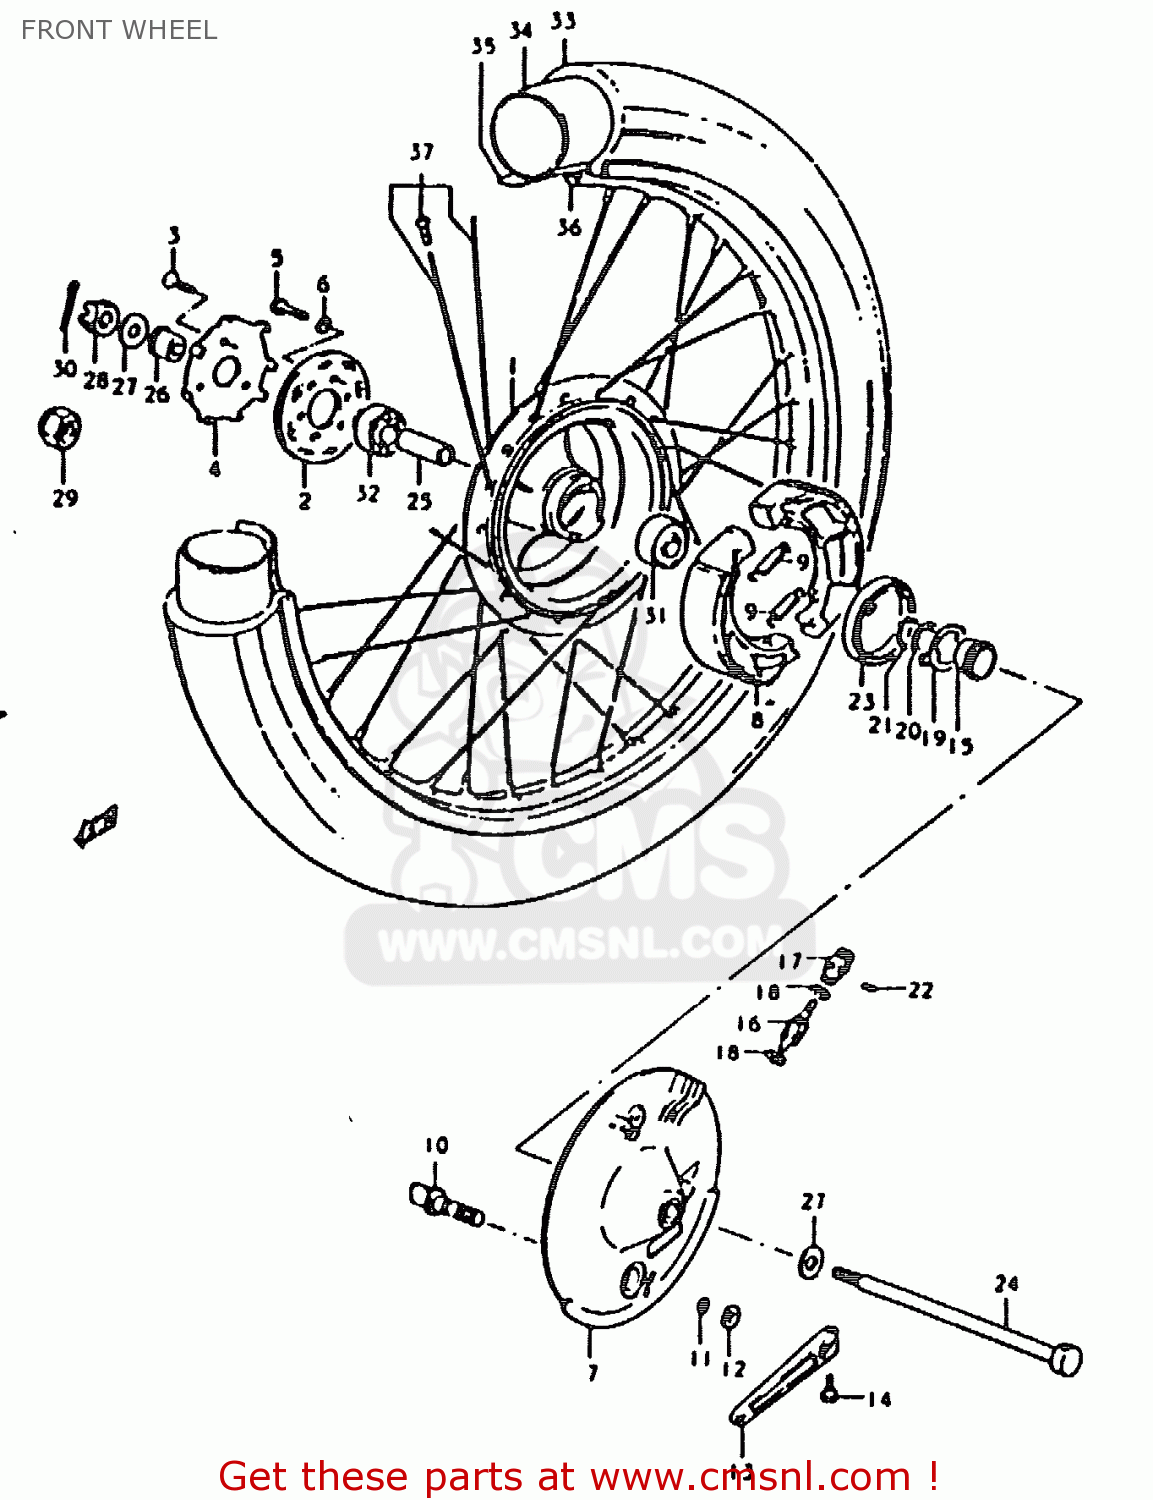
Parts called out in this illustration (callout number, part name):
1	HUB,FR WHEEL
2	FLANGE,FR HUB,R
3	SCREW
4	RETAINER,FR HUB BEARING,R
5	BOLT, UPPER
6	LOCK WASHER
7	PANEL,FRONT HUB
8	SHOE,BRAKE
9	SPRING(L:34)
10	CAM,FRONT BRAKE
11	O-RING (D:2.4 ID:13.8)
12	WASHER (14.5X22X1.6)
13	LEVER,FRONT BRAKE CAM
14	BOLT
15	GEAR,SPEEDOMETER
16	PINION,SPEEDOMETER
17	BUSH,METER GEAR OUTER
18	WASHER (5.1X9X0.4)
19	DRIVER,SPEEDOMETER GEAR
20	WASHER(18.5X24X1)
21	CIRCLIP
22	SCREW
23	OIL SEAL (43X58X7)
24	AXLE,FRONT
25	SPACER (12.6X19X52)
26	SPACER,FR AXLE,R
27	WASHER
28	NUT 12MM
30	COTTER PIN
31	BEARING
32	BEARING, RH
33	TIRE,FR
34	TUBE
35	PROTECTOR,WHEEL,INNER
36	RIM,FR WHEEL(1.60X21)
37	SPOKE SET,FRONT
